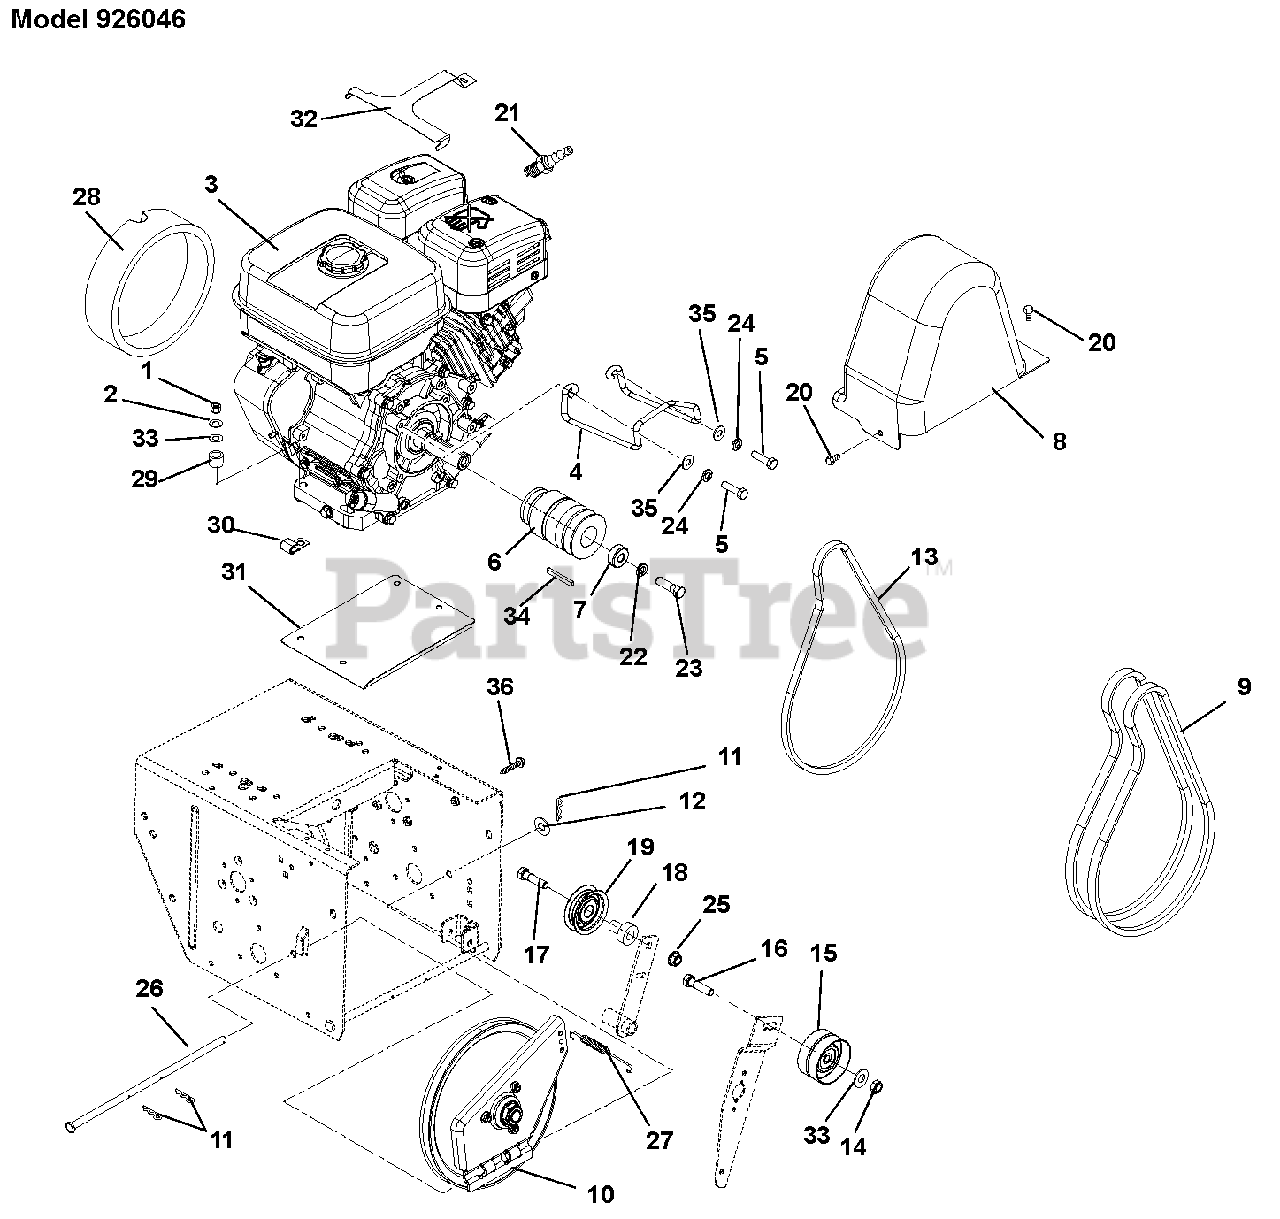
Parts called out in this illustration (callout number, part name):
1	Nut, Hex .31-18
2	Washer, Lock .312 x .097
3	Engine, Subaru EX27 All-Season
4	Belt Finger
5	Bolt, Hex .31-24 x .75
6	Sheave, Engine
7	Bushing, Spacer
8	Cover, Belt
9	V-Belt, Matched Set, Brush
10	Plate, Swing Assembly
11	Hair Pin
12	Washer, Flat Steel .406 x .812 x .065
13	V-Belt, Drive
14	Nut, Locking Center Jam .38-16
15	Idler, Flat
16	Bolt, Round Head Square Short Neck .38-16 x 1.75
17	Bolt, Hex .31-18 x 1.25
19	Idler
20	Screw, Tapping Large Hex Washer Head Thread Rolling .25-20 x .50
21	Plug, Spark
22	Washer, Lock .44 x .109
23	Bolt, Hex .44-20 x 1.50
24	Washer, Lock .312 x .097
25	Nut, Locking Top Flange .31-18
26	Rod, Pivot
28	Foam Cover, Recoil
29	Bushing, Sleeve
32	Guard, Snow
33	Washer, Flat Steel .38 x .875 x .083
34	Key .25 x .25 x 2.25
35	Washer, Flat Steel .344 x .688 x .065
36	Screw, Tapping Hex Washer Head Thread Rolling .25-20 x 1.50
